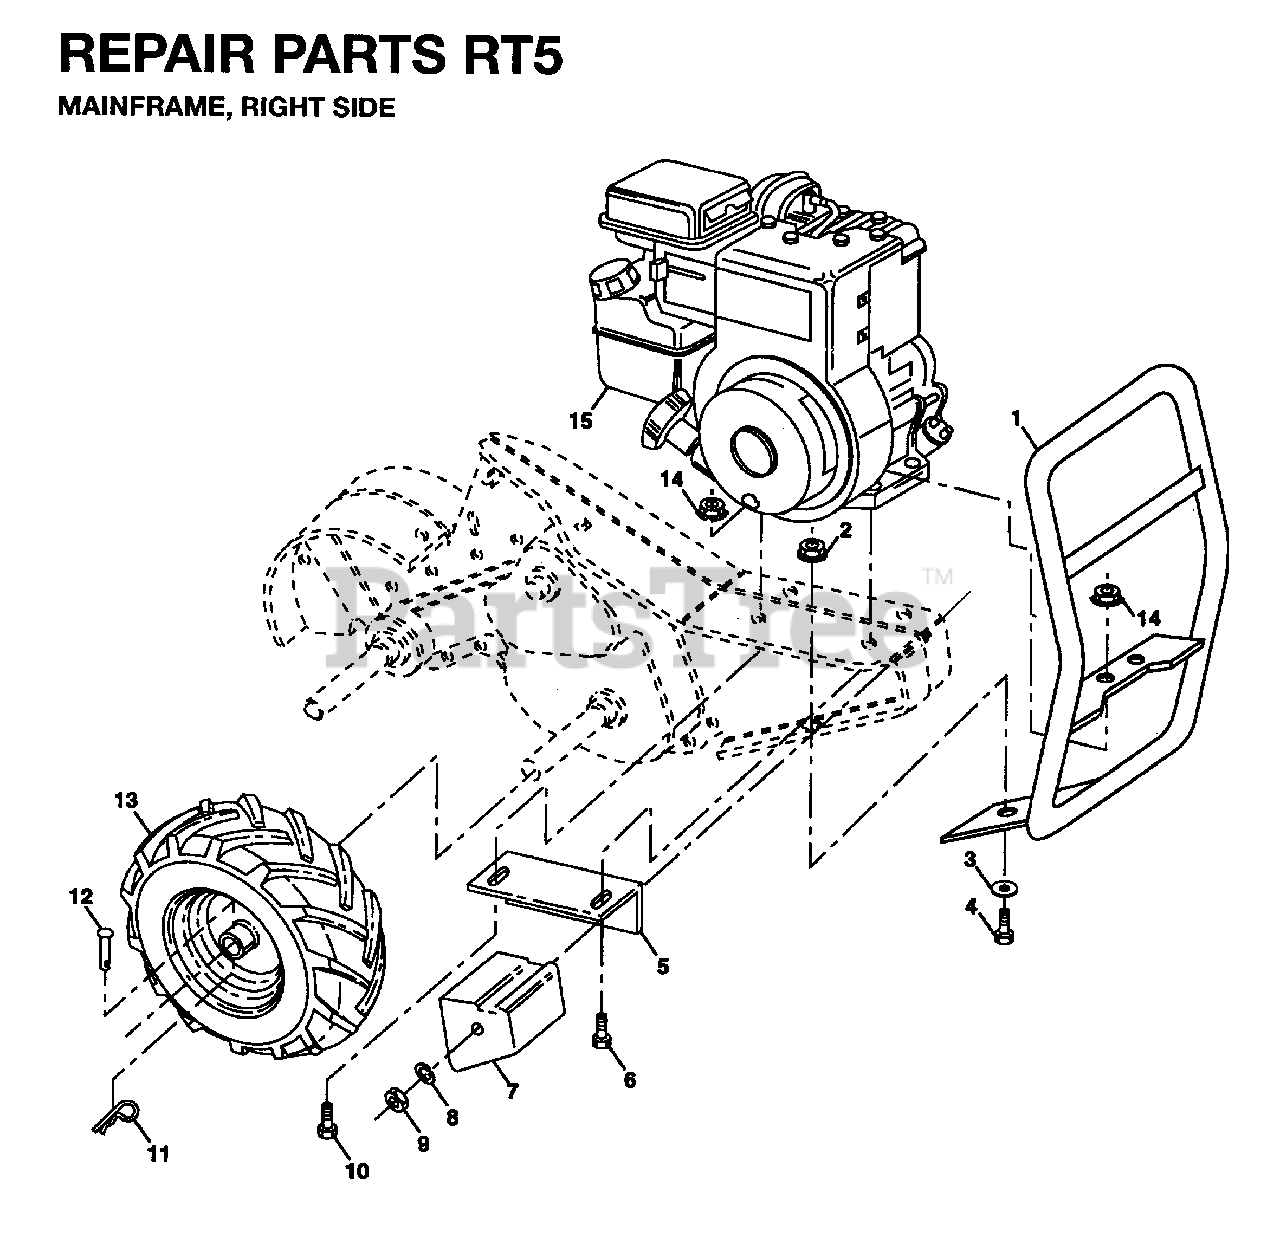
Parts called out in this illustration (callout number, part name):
1	BUMPER
2	LOCKNUT
3	WASHER - 15X7.3X1.6
4	BOLT
5	BRACKET RH CRT
7	COUNTERWEIGHT, RH
8	WASHER, LOCK 3/8
9	NUT.HEX.3/8-16UNC
10	HEX BOLT
11	RETAINER M
12	RIVET,DRILLED
14	LOCKNUT
5320651-39	VALVE STEM LT
5321289-52	WHEEL.8X2-3/4.TILLER /RIM ONLY
